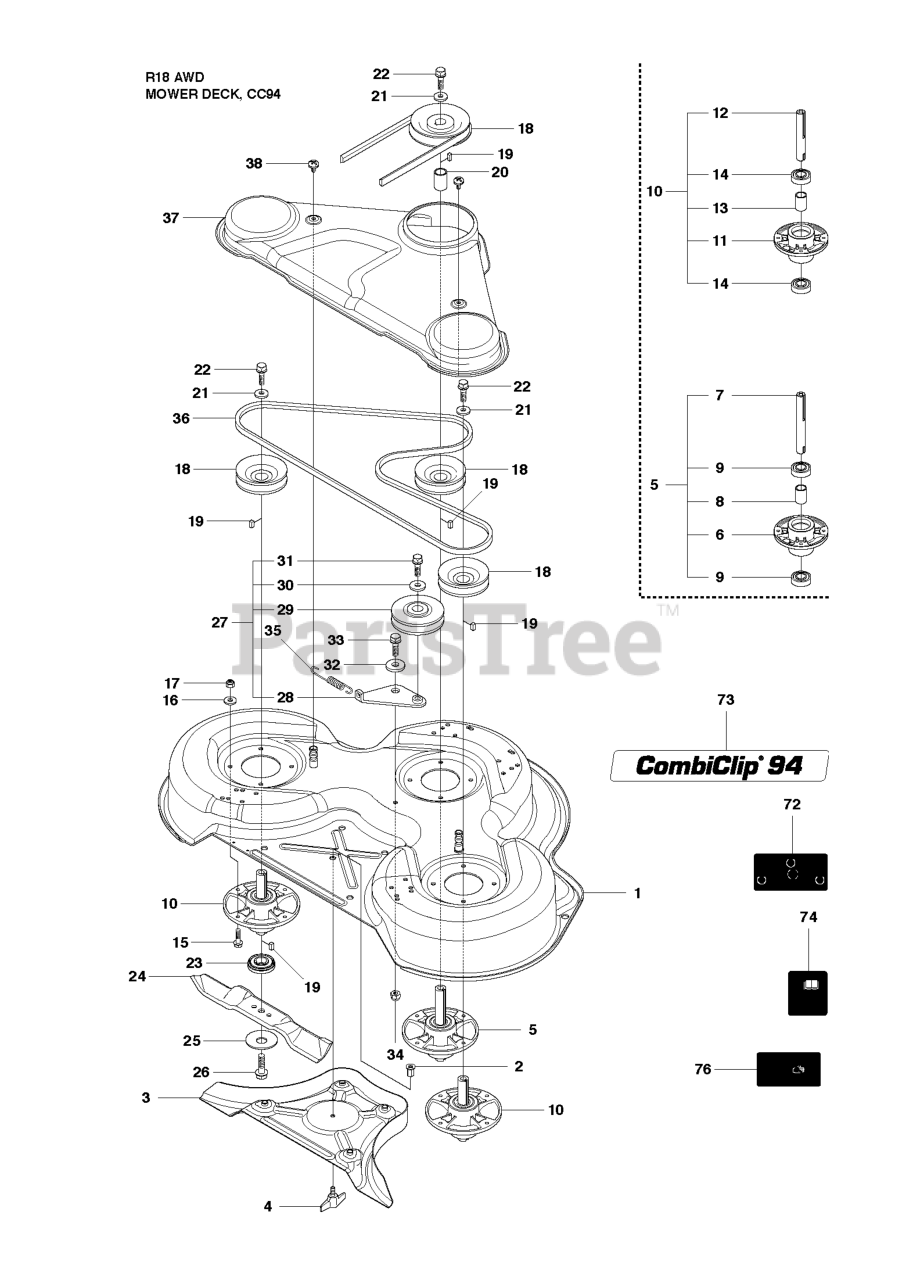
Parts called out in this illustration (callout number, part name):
1	CUTTING DECK W/PLUG GREY RIDER
3	PLUG C93 & C94
5	SPINDLE ASSY
6	BEARING HOUSING
10	RP SPINDLE ASSY
11	BEARING HOUSING
14	BALL BEARING
16	WASHER BRB 8.4X17
17	LOCKNUT M8
25	WASHER
27	BELT TENSIONER ASSY
28	BELT TENSIONING ARM
32	WASHER
34	LOCKNUT M8
37	BELT COVER C93 & C94 GREY
